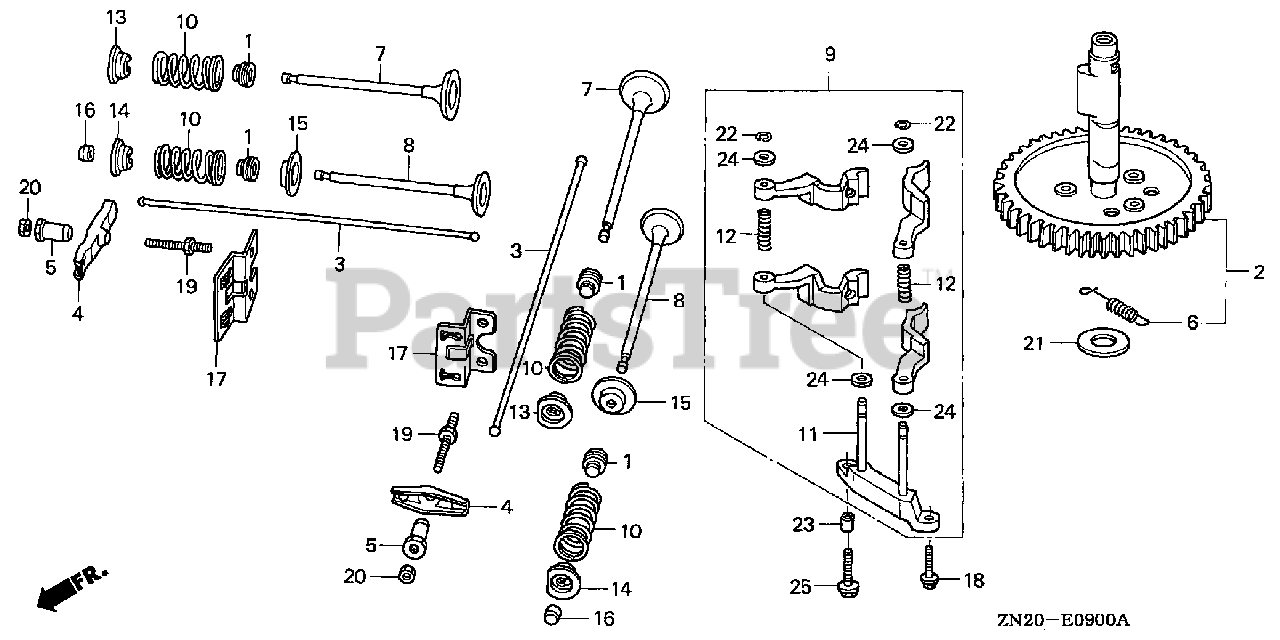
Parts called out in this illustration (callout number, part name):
1	SEAL, VALVE STEM
2	CAMSHAFT ASSY.
3	ROD, PUSH
4	ARM, VALVE ROCKER
5	PIVOT, ROCKER ARM
6	SPRING, WEIGHT RETURN
7	VALVE, IN.
8	VALVE, EX.
9	LIFTER ASSY., VALVE
10	SPRING, VALVE
11	SHAFT, VALVE LIFTER
12	SPRING, VALVE LIFTER
13	RETAINER, IN. VALVE SPRING
14	RETAINER, EX. VALVE SPRING
15	SEAT, VALVE SPRING
16	ROTATOR, VALVE
17	GUIDE, PUSH ROD
18	BOLT, FLANGE (5X16)
19	BOLT, PIVOT (8MM)
20	NUT, PIVOT ADJ.
21	WASHER, THRUST (17.2MM)
22	CLIP, GOVERNOR HOLDER
23	PIN A, DOWEL (8X12)
24	WASHER, PLAIN (6MM)
25	BOLT, FLANGE (6X25)
